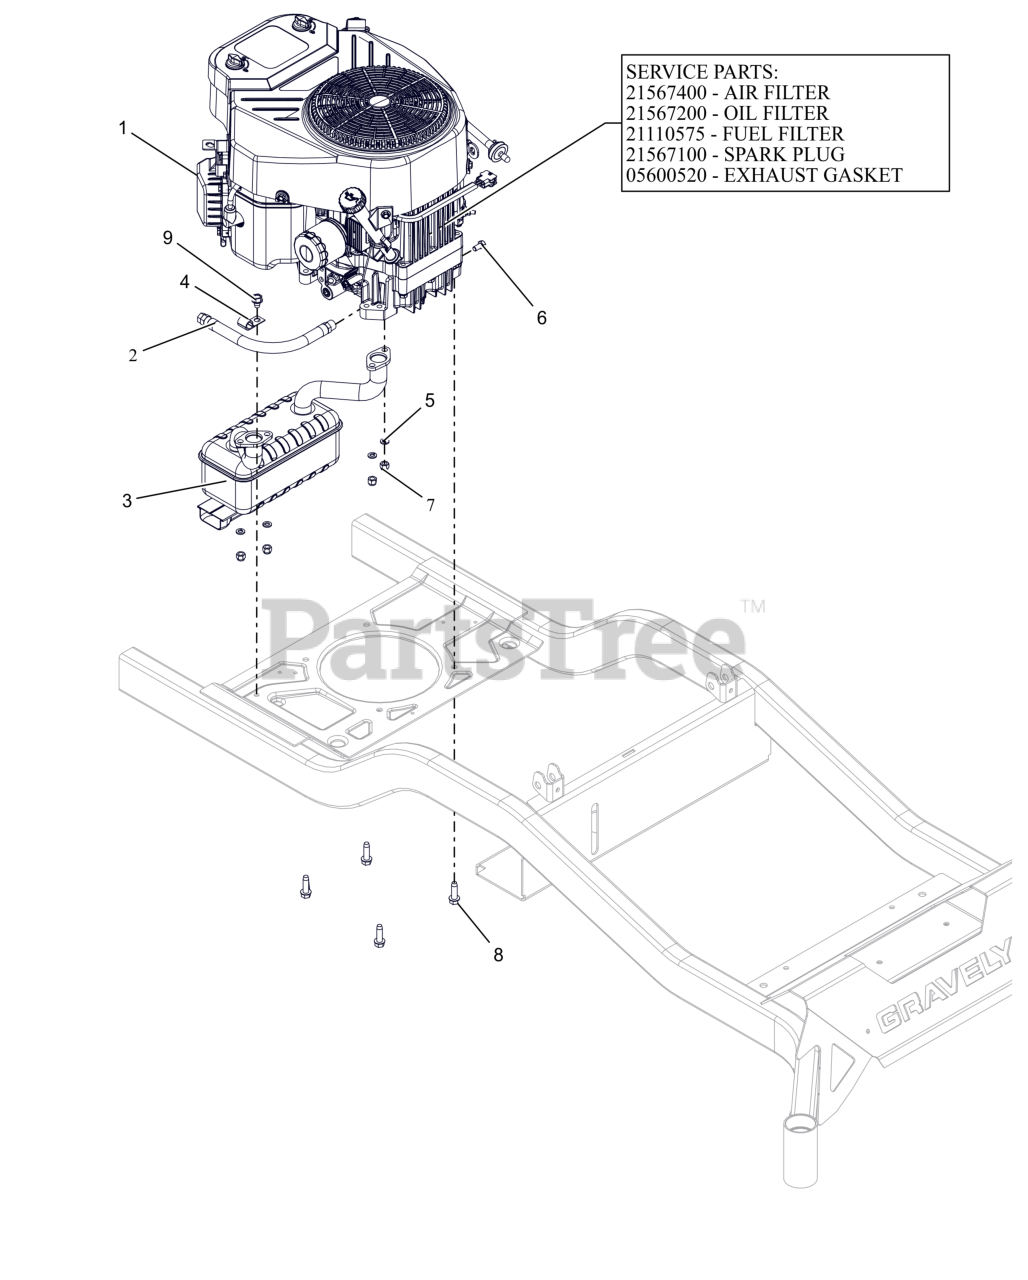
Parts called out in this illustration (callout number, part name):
1	ENGINE, LONCIN 764cc
1	FILTER, AIR
1	FILTER, OIL LONCIN
1	FILTER, FUEL
1	PLUG, SPARK
1	GASKET, MUFFLER LONCIN
2	HOSE, OIL DRAIN
3	MUFFLER,
5	WSHR,LK-REG .312X.078 ZCC
6	BLT, HEX .31-18X.625 G5 ZCC
7	NUT,NYL M8-1.25 G8.8 ZCC
8	SCR,TAP .375-16X1.25HWH TR ZCC
9	SCR,TAP .375-16X.50 HWH TR ZCC
